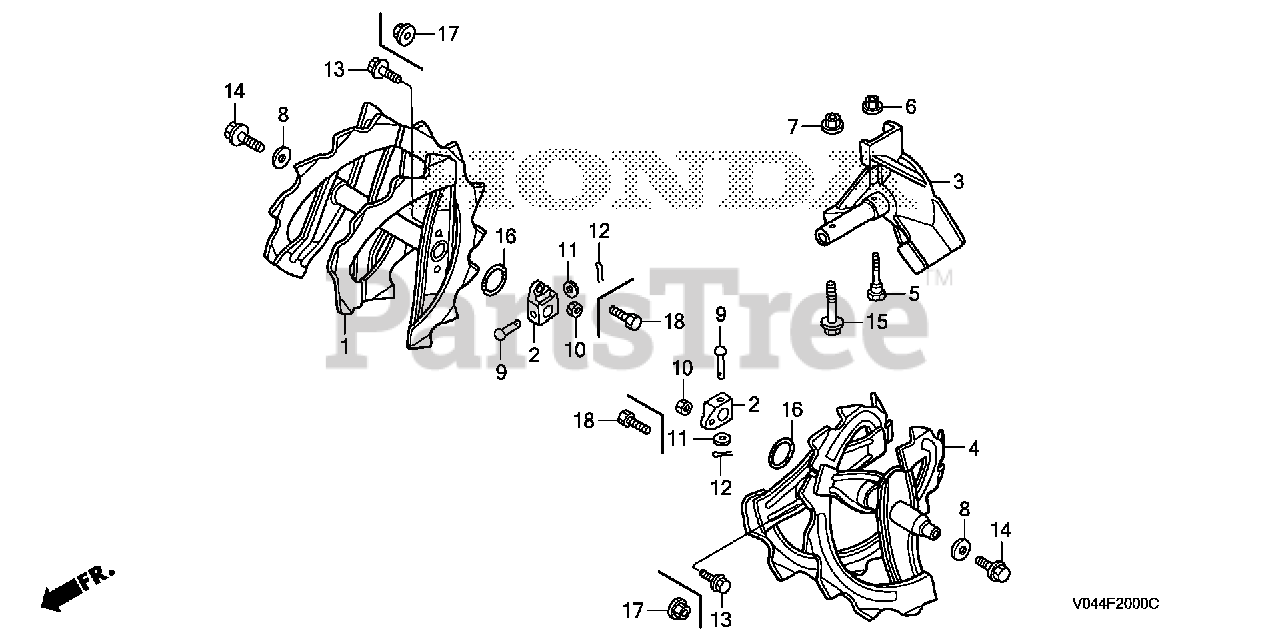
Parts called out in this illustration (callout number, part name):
2	BOSS, LOCK BOLT
5	BOLT, LOCK
6	NUT, SELF-LOCK (6MM)
7	NUT, FLANGE (M8X1.25) (SELF-LOCK)
8	WASHER (23X8.3X3.2)
9	PIN (7X40)
10	NUT, HEX. (6MM)
11	WASHER, PLAIN (7MM)
12	PIN, SPLIT (3.0X25)
12	PIN, SPLIT (3.0X45)
13	BOLT, FLANGE (6X16)
14	BOLT, FLANGE (8X16)
15	BOLT, FLANGE (8X35)
16	O-RING (19.8X1.9) (ARAI)
17	NUT, SELF-LOCK (6MM)
18	BOLT, HEX. (6X16)
